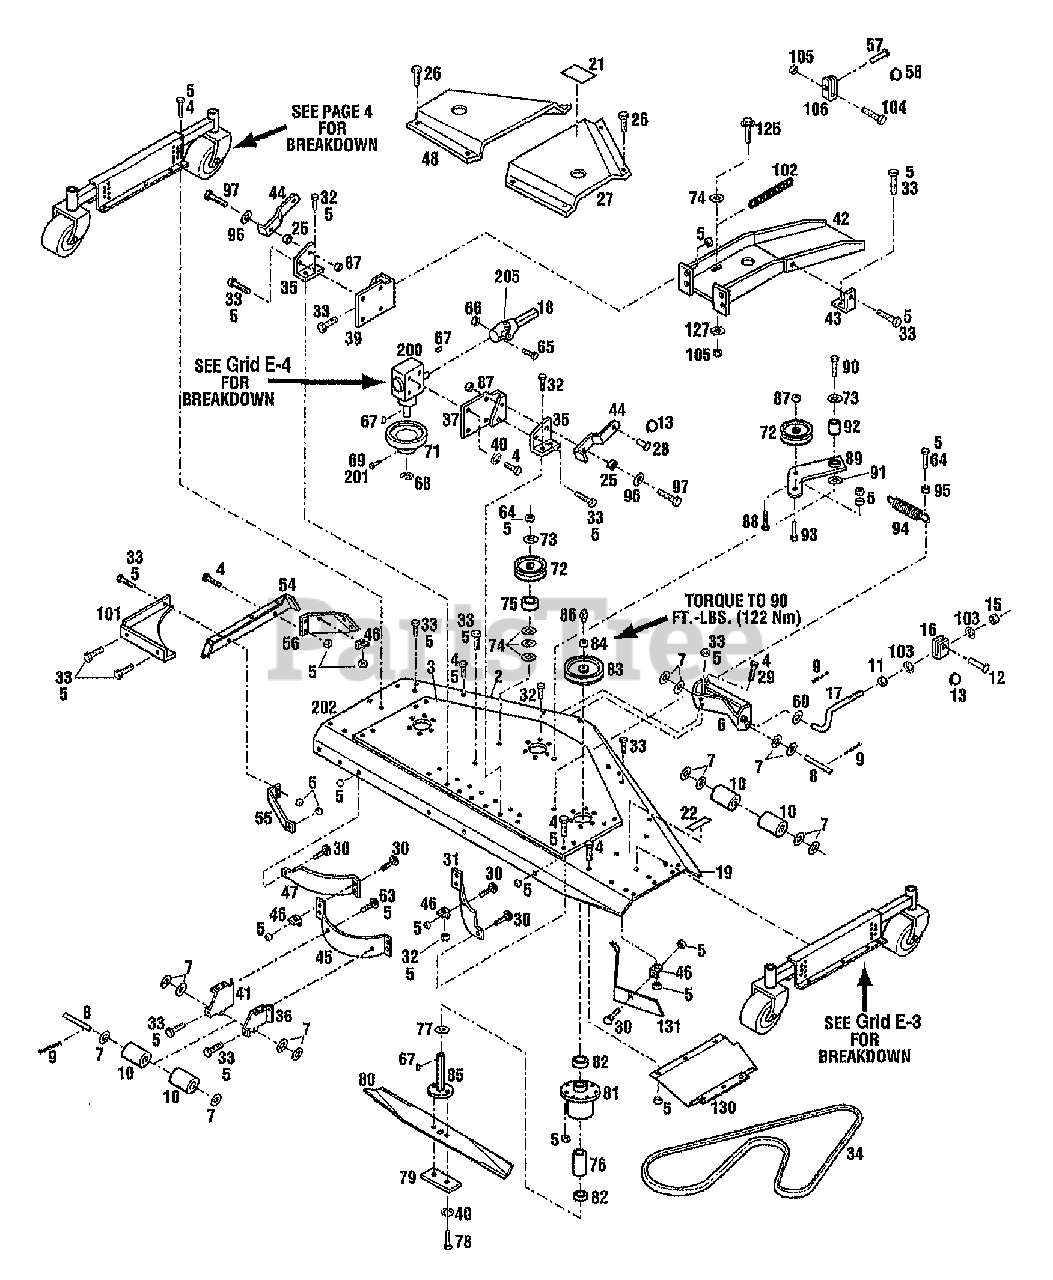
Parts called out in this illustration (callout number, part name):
2	BASE-FRONT LH
3	DOUBLER-BASE
4	SCR-HH 3/8-16X.75 G5 ZP
5	NUT-LOCK 3/8-16
6	BRKT-DRAG FRONT
7	WASHER-1.5X.812X.134 ZP
8	SHAFT-ROLLER
9	PIN-COTTER .120X1.25 ZP
11	NUT
12	PIN-CLEVIS .62X2.50 ZP
13	RING-COTTER
15	NUT-H/LK 3/4-10
17	LINK-HITCH
18	ASSM-DRIVE
19	BASE-FRONT RH
21	DECAL-BELT DRIVE
22	DECAL-CUTTING LINE
25	SPACER-TUBULAR
26	SCR
27	COVER-BELT RH
28	PIN-CLEVIS .625X1.44
29	NUT-H/LK 3/8-16
30	BOLT-3/8-16 X 3/4
32	SCR-HH 3/8-16X1.25
33	SCR-HH 3/8-16X1.0 G5 ZP
34	BELT-V
35	BRKT-MOUNTING
36	BRKT-ROLLER RH
37	BRKT-GEAR BOX RH
39	BRKT-GEAR BOX LH
40	WASHER-LK .375 @ DEPL
41	BRKT-ROLLER LH
42	BASE BRIDGE
43	BRKT-SUPPORT
44	LINK-DRAG
45	BAFFLE-CENTER
46	BRKT-BAFFLE
47	BAFFLE-LH
48	COVER-BELT LH
54	BASE-END
55	BAFFLE-REAR CORNER
56	BAFFLE-FRONT CORNER
57	PIN-CLEVIS .375 X .937 ZP
58	RING-CIRCLE COTTER
60	WASHER-1.38 X.765X .06 ZP
63	SCR-CARR 3/8-16X1.00
64	SCR-HH 3/8-16X2.0 G5 ZP
65	SCR-SOC HD CAP 1/4-20
66	NUT-HT LK 1/4-20
67	KEY-WOODRUFF .25X.875
68	RING-RETAINING
69	SCR-SQ HD SET 5/16X3/4
71	SHEAVE-DRIVE
72	PULLEY-IDLER
73	WASHER-.986X.437X.083 ZP
74	WASHER-1.12X.378X.125
75	SPACER-.5X.385X.437
76	SLEEVE
77	SHIM-1.25X1.01X.06
78	SCR-HH 3/8-24X1.0 G5 ZP
79	PLATE-BLADE
81	HOUSING-SPINDLE
82	BEARING-BALL
83	SHEAVE-BLADE
84	NUT-H/LK
85	ASSM-BLADE SHAFT
86	FITTING-GREASE 1/4-28X2.00
87	NUT-TOP LOCK 1/2-13 ZP
89	ARM-IDLER
90	SCR-HH 3/8-16X1.5 G5 ZP
91	WASHER
94	SPRING-EXTENSION
95	NUT-HEX/JAM 3/8-16
96	WASHER-1/2 FLAT
97	SCR-HH 1/2-13X1.75 G5 ZP
101	PLATE-BAFFLE
102	CHAIN
103	WASHER-LK 1.264X.76X.188
104	SCR-HH 5/16-18X1.25 G5ZP
105	NUT-H/LK 5/16-18
125	SCR-HFLK 5/16-18X1.00 ZP
127	WASHER-FLAT 5/16 SAE
130	DISCHARGE DEFLECTOR
131	BAFFLE, RIGHT CENTER
200	GEARBOX-RIGHT ANGLE
201	LOCTITE-242 (.5 ML TUBE)
202	ASSM-MOWER BASE W/DECALS
205	KIT-CROSS REPAIR
